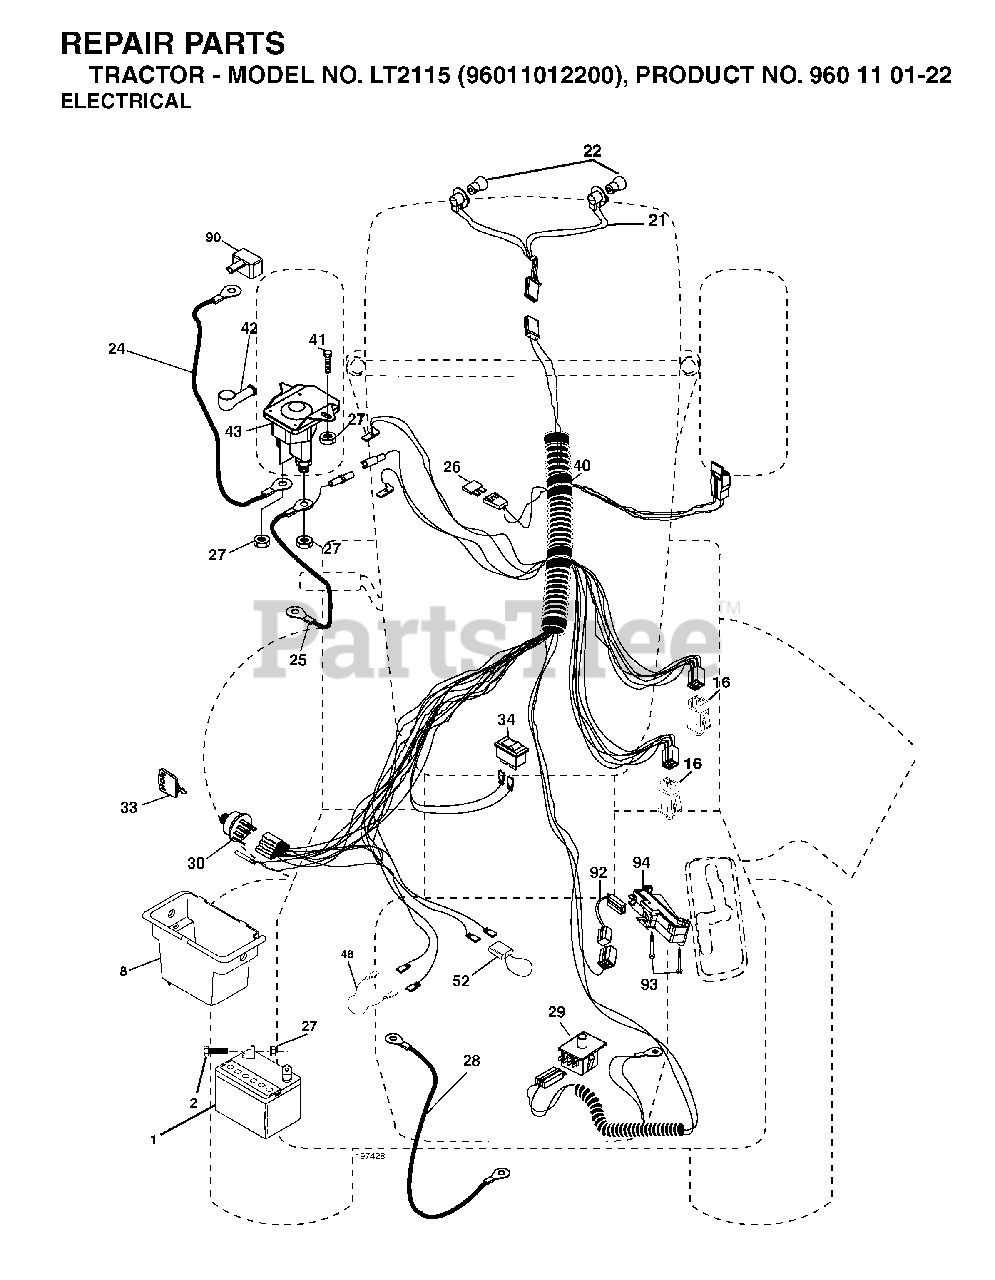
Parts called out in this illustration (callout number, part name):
1	BATTERY 12V .35 AMP
8	BOX.BATTERY.FENDER
16	SWITCH INTERLOOK PUSH-IN
21	HARNESS ASSY LIGHT
22	LIGHTBULB
24	BATTERY CABLE GT
25	CABLE BATTERY
26	FUSE 20AMP
27	NUT
28	CABLE T
29	SWITCH.SEAT.DP W/RAMPS
30	SWITCH.IGN.DELTA.W.LGH.ROS
33	KEY MLD GEN DELTA
34	SWITCH LT
42	TERMINAL COVER
43	SOLENOID.W/BRASS.PLUNG
52	WIRE PROTECTION LOOP
90	COVER TERMINAL
92	HARNESS.PIGTAIL.CONSLE
93	SCREW.PLASTITE
94	MODULE.REVERSE.ROS
